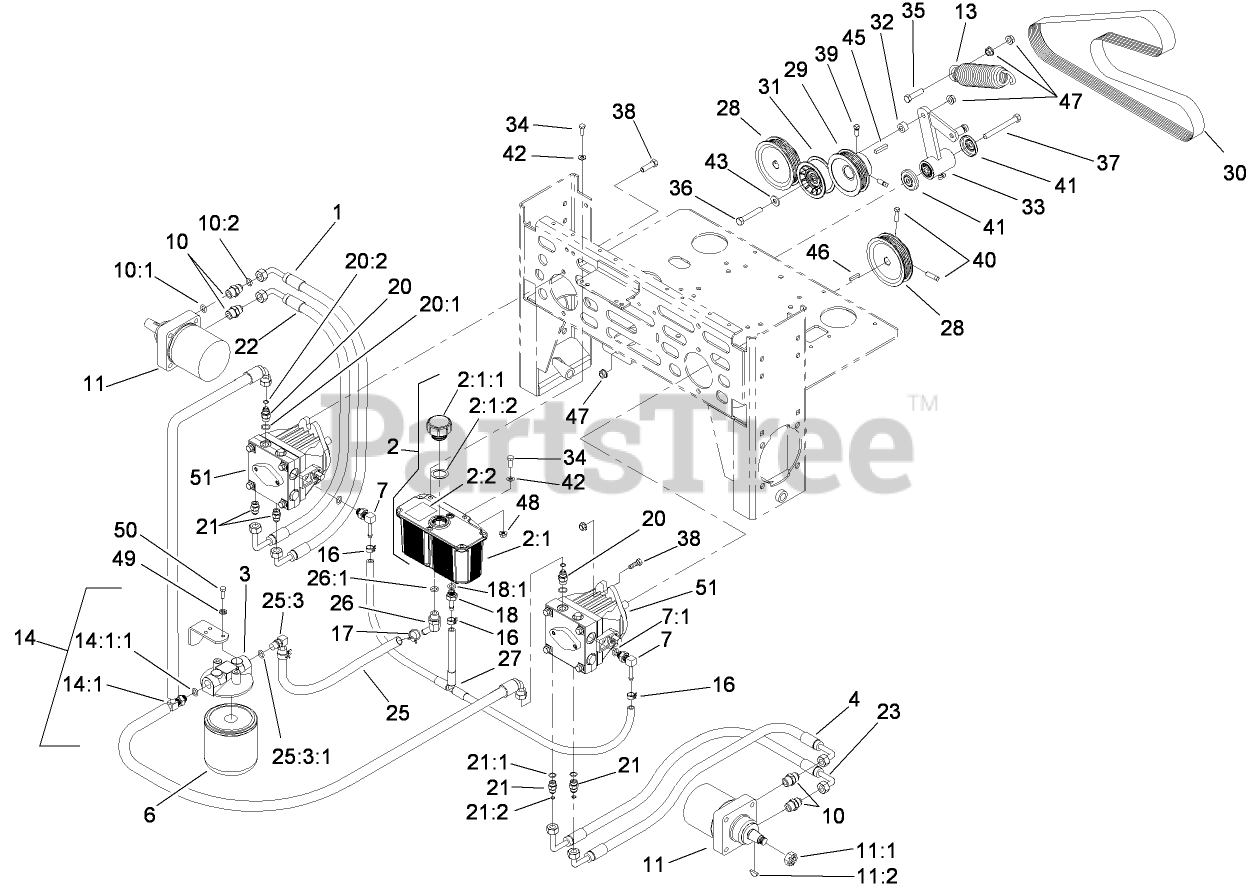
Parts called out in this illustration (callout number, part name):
1	HYD HOSE ASM
2	HYD Reservoir ASM
2:1	Reservoir-HYD
2:1:1	CAP-RESERVOIR, HYD
2:1:2	GASKET-CAP
2:2	DECAL-TANK, HYD
3	HEAD-FILTER
4	HYD HOSE ASM
6	FILTER-OIL, HYD (WINTER)
6	FILTER-OIL, HYD
7	ELBOW-90 DEG
7:1	O-RING
10	Fitting-Straight
10:1	O-RING
10:2	O-Ring
11	MOTOR-WHEEL
11:1	NUT-HH
11:2	KEY-WOODRUFF
13	Spring-Extension
14	HYD HOSE ASM
14:1	ADAPTER-RUN, TEE
14:1:1	O-RING
16	Clamp-Hose
17	Clamp-Hose
18	Adapter-Straight
18:1	O-RING
20	FITTING-STRAIGHT
20:1	O-Ring
20:2	O-RING
21	FITTING-STRAIGHT
21:1	O-RING
21:2	O-Ring
22	HYD HOSE ASM
23	HYD HOSE ASM
25	HYD HOSE ASM
25:3	FITTING-BARB
25:3:1	O-RING
26	FITTING-BARBED, 45 DEG
26:1	O-RING
27	HYD Hose ASM
28	SHEAVE
29	SHEAVE
31	PULLEY-FLAT IDLER
32	SPACER
33	PUMP IDLER ASM
34	SCREW-HH
35	SCREW-HH
36	SCREW-HH
37	SCREW-HH
38	SCREW-HH
39	SCREW-SET
40	SCREW-SET
41	GUARD-TOP
42	WASHER-FLAT
43	WASHER-FLAT
45	KEY-SQUARE
46	KEY-SQUARE
47	NUT-HHF, WHIZ
48	NUT-HF
49	WASHER-LOCK
50	SCREW-HH
51	PUMP-HYD
